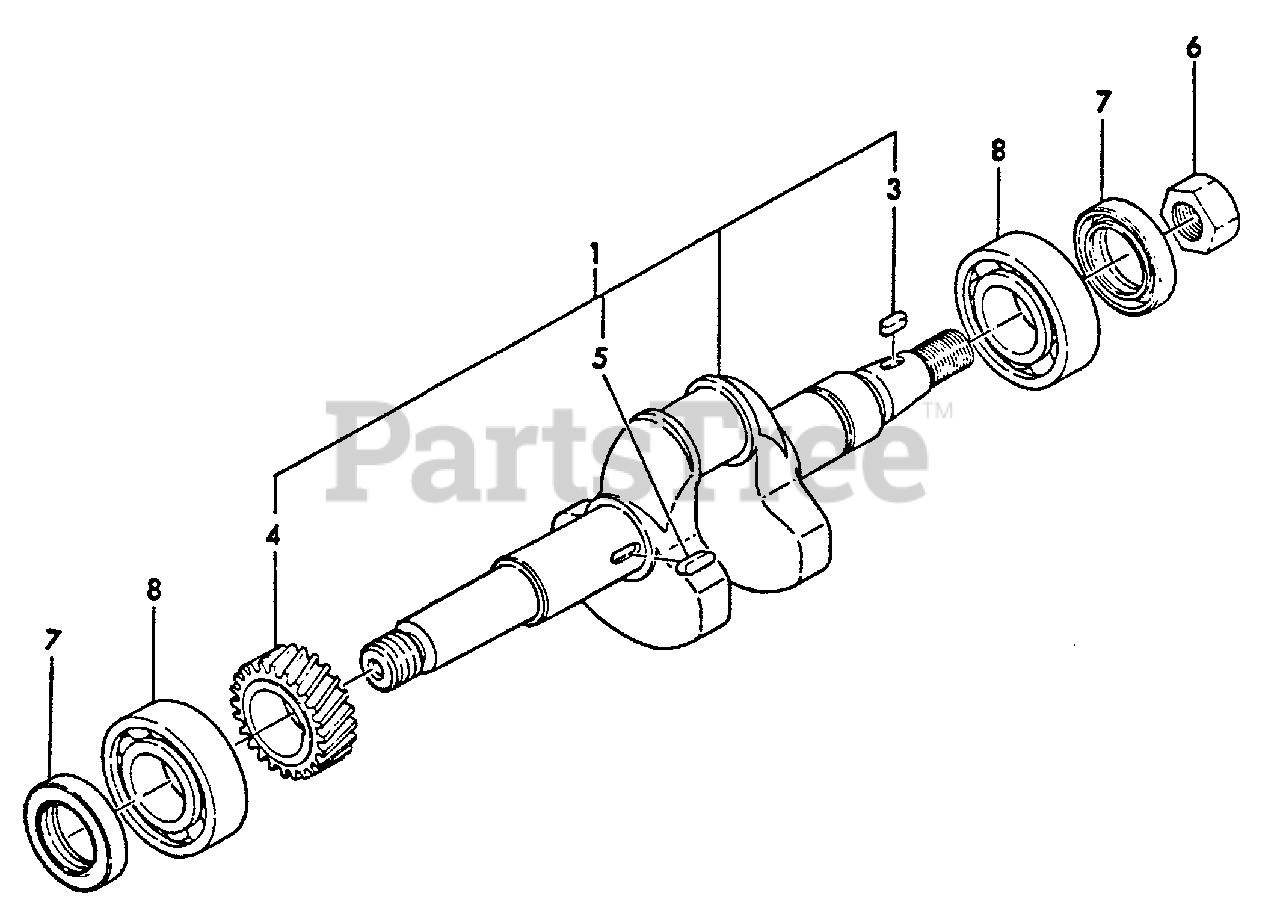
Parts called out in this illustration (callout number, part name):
1	CRANKSHAFT ASSY
3	KEY - 4×10
4	GEAR, CRANKSHAFT
5	KEY 4×12
6	NUT - 14
7	SEAL, OIL
8	BEARING, BALL
